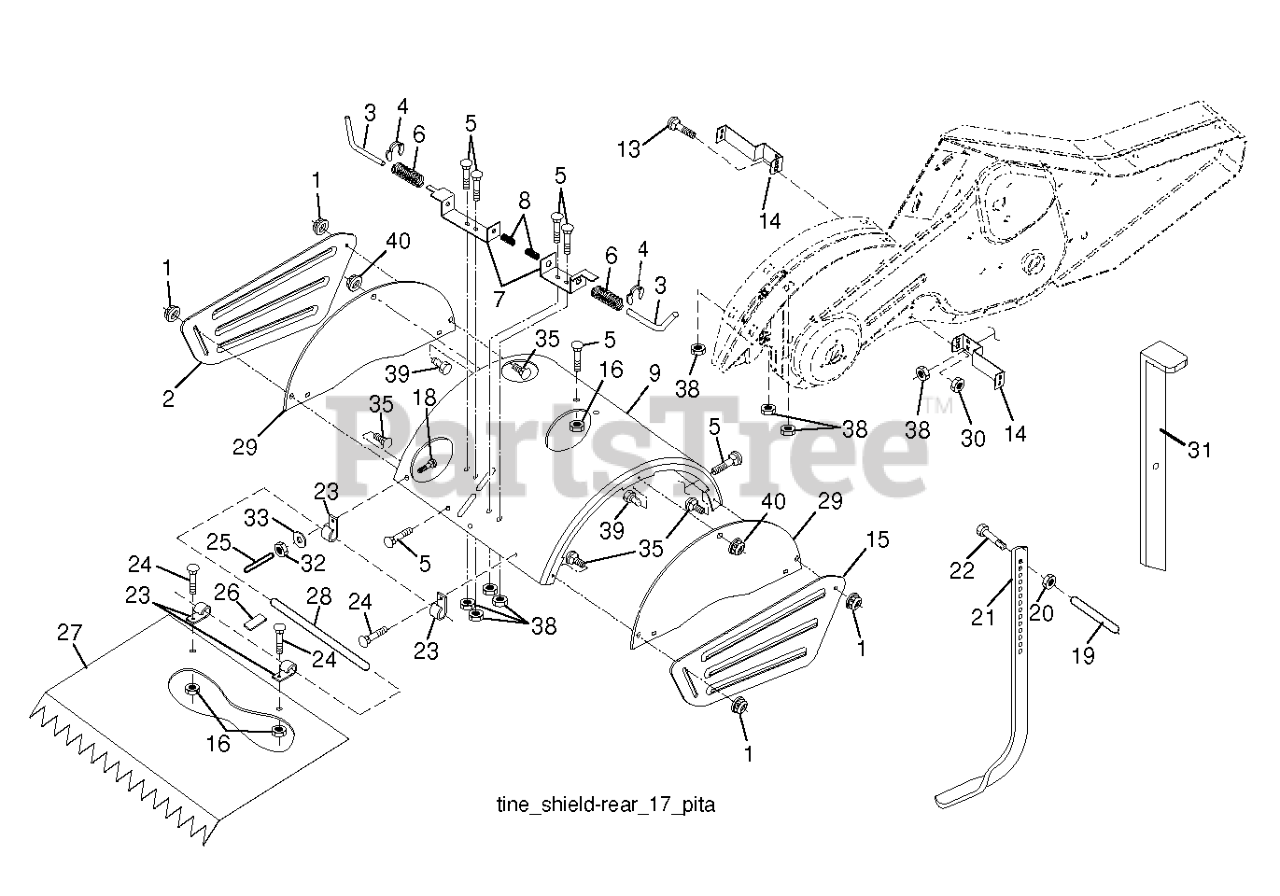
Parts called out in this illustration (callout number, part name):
1	NUT.FLANGE.5/16
2	SHIELD.PNT.SIDE.OUTER.LH.ORANG
3	STAKE PIN TI
4	RING, KLIP
5	BOLT, RDHD SQNK 5/16-18 X 3/4
7	BRACKET
8	SPRING CRT
9	SHIELD.TINE.DRT17.TILLER.ORANG
13	BOLT.CARRIAGE.5/16-18
14	BRACKET.TINE.SHIELD.BLACK
15	SHIELD.SIDE OUTER.RH.ORANGE
16	NUT T
20	NUT.HEX.3/8-16UNC
21	REPL BY 532 10 21-56
22	BOLT.375-16
25	VINYL CAP TI
26	PAD IDLER TI
27	SHIELD.LEVELING.17".ORANGE
28	PIN.HINGE.TILLER
29	SHIELD.TINE.SIDE.ORANGE
30	LOCKNUT-FLANGE 5/16-18
31	STAKE.DEPTH.DRAG.BLACK.TILLER
32	NUT
33	LOCKWASHER
35	BOLT.CARR.5/16-18X5/8.SHORT
38	NUT
39	BOLT.HEX.HD.WASHER.5/16-18X.75
40	NUT.SPEED.5/16-18
